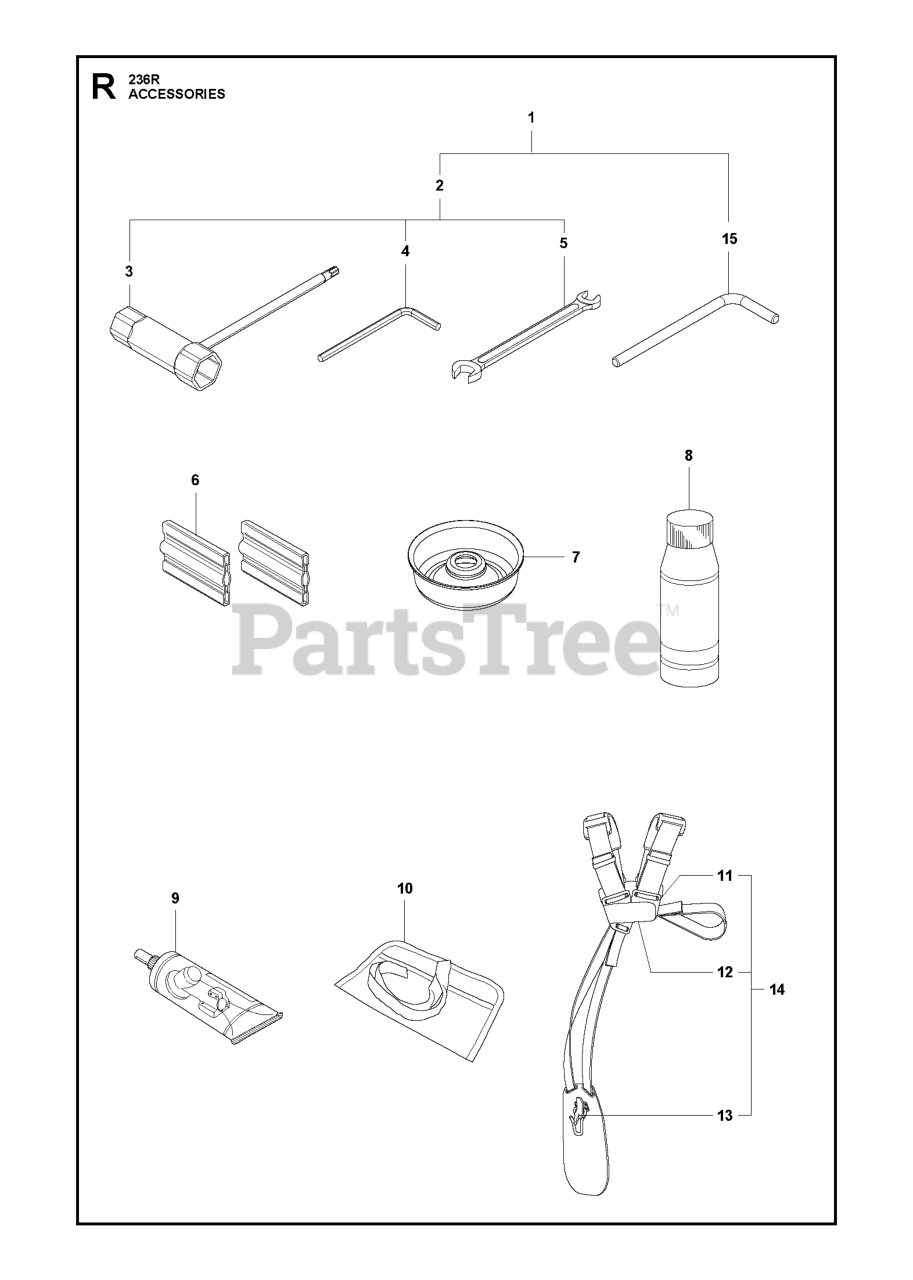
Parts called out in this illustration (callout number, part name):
5	WRENCH SPANNER
6	BAR GUARD
6	TRANSPORT GUARD
7	SUPPORT CUP
8	Air Filter Oil 1l.
9	BEVEL GEAR GREASE
13	HOOK, CPL.
14	HARNESS DUO
